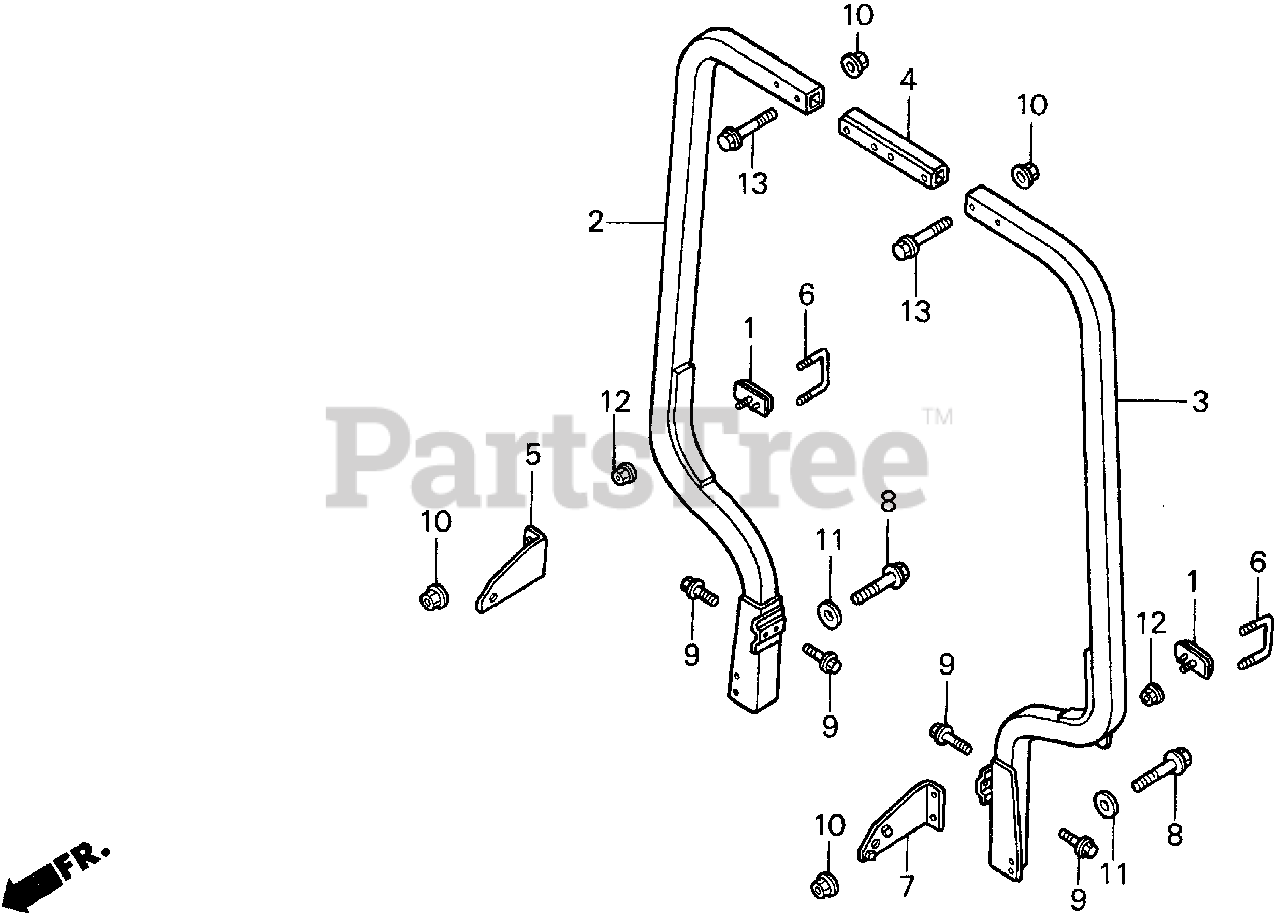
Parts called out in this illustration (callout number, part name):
1	REFLECTOR, REFLEX
2	ROPS., R. *NH1* (BLACK)
3	ROPS., L. *NH1* (BLACK)
4	JOINT, ROLL OVER PROTECTIVE STRUCTURE
5	PLATE, R. SEAT BELT
6	U-BOLT (10X74)
7	PLATE, L. SEAT BELT
8	BOLT, FLANGE (10X30)
9	BOLT, HEX. (10X25)
10	NUT, U (10MM)
11	WASHER (10.3X25)
12	NUT, FLANGE (5MM)
13	BOLT, FLANGE (10X60)
